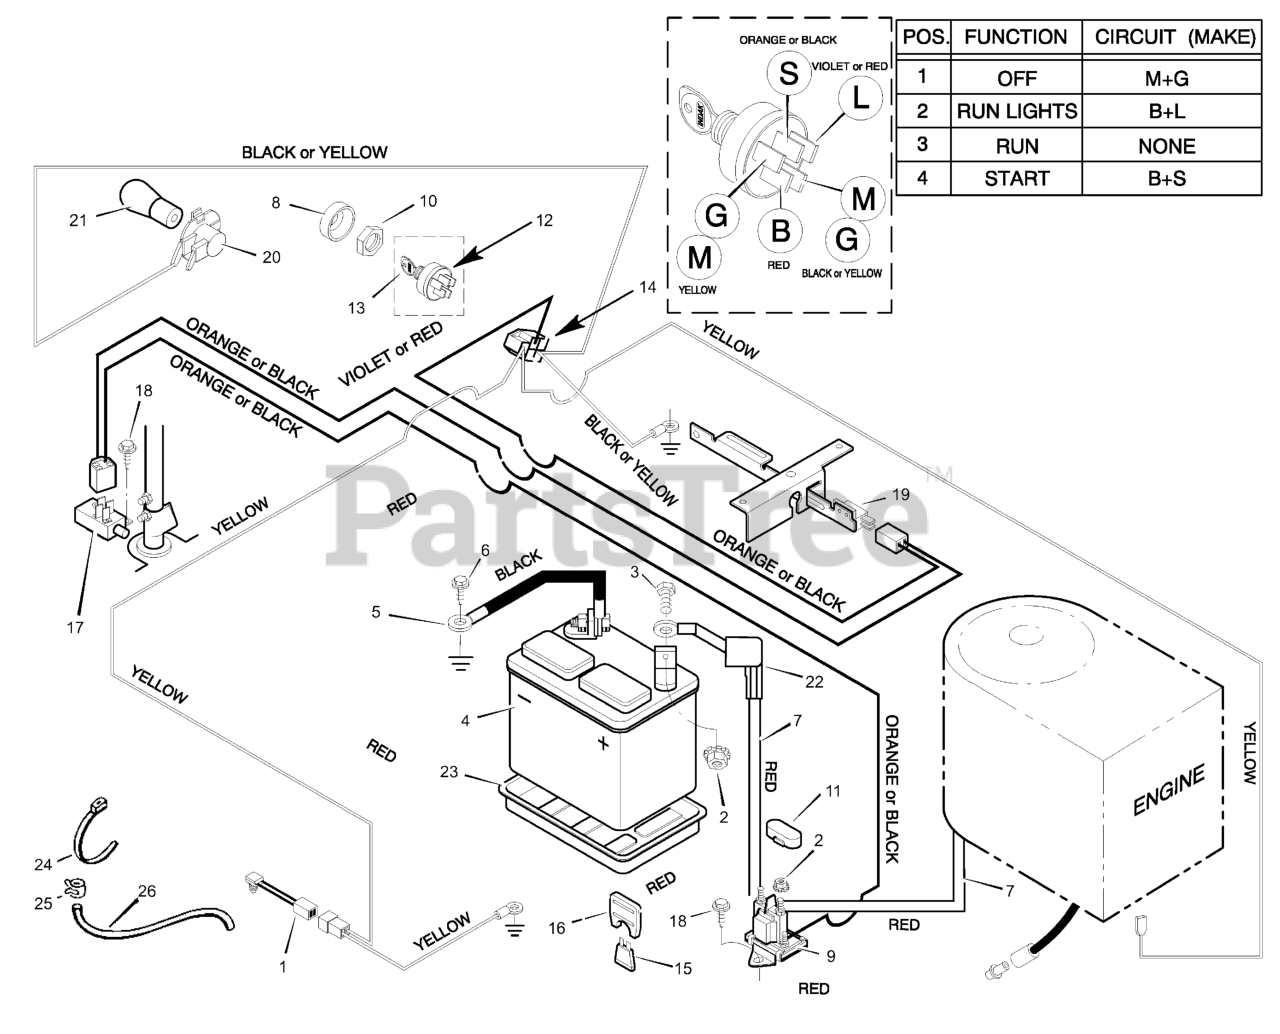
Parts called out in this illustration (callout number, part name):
1	Switch, Seat Sensor
2	Locknut
4	Battery
5	Cable, Battery Ground
7	Cable, Red Battery
8	Cap, Ignition
9	Solenoid
10	Nut, Hex
11	Cover, Solenoid
12	Switch, Ignition
13	Key, Ignition
14	Harness, Chassis Wire
16	Holder, Fuse
17	Switch, Limit
19	Switch, Limit
20	Socket, Light
21	Bulb, Light
22	Cover, Terminal
23	Tray, Battery
26	Tube, Drain
